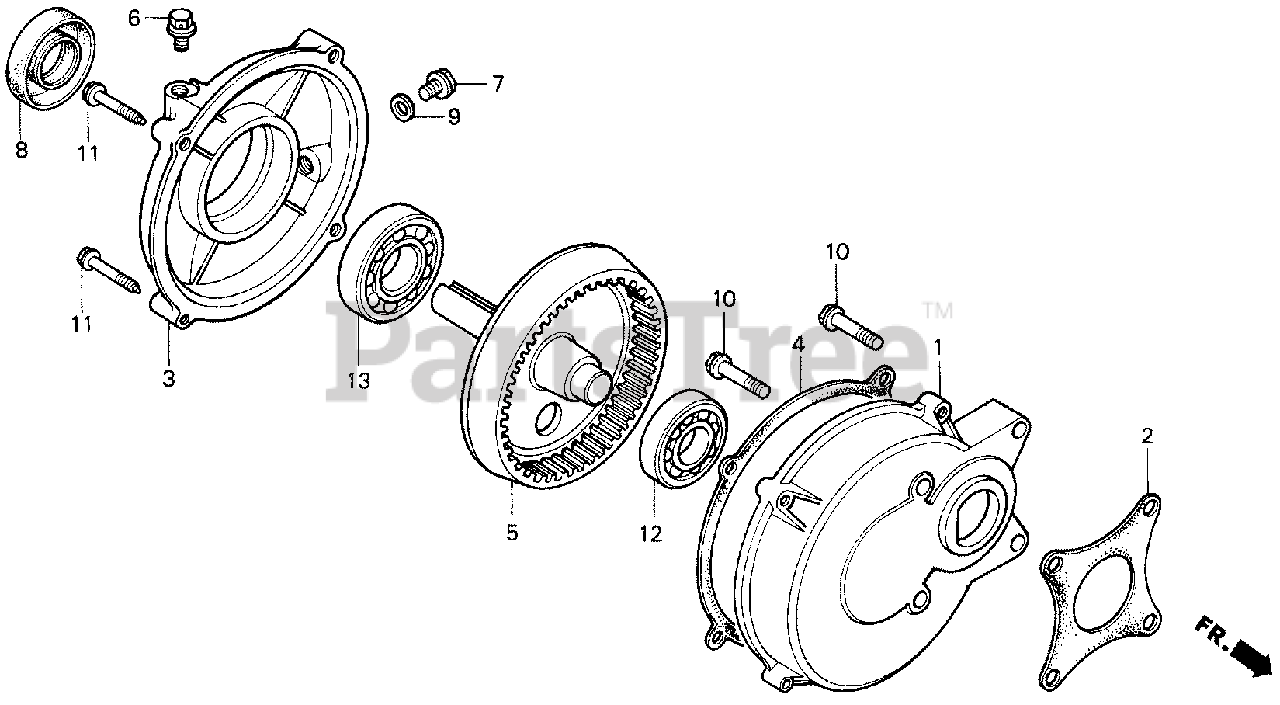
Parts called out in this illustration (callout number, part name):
1	CASE, REDUCTION
2	GASKET, REDUCTION CASE
3	COVER, REDUCTION
4	GASKET, REDUCTION COVER
5	SHAFT, P.T.O.
6	BOLT, BREATHING
7	BOLT, DRAIN PLUG
8	OIL SEAL (25X41X6)
9	WASHER, DRAIN PLUG (12MM)
10	BOLT, FLANGE (8X32)
11	BOLT, FLANGE (8X35)
12	BEARING, RADIAL BALL (6204)
13	BEARING, RADIAL BALL (6305)
